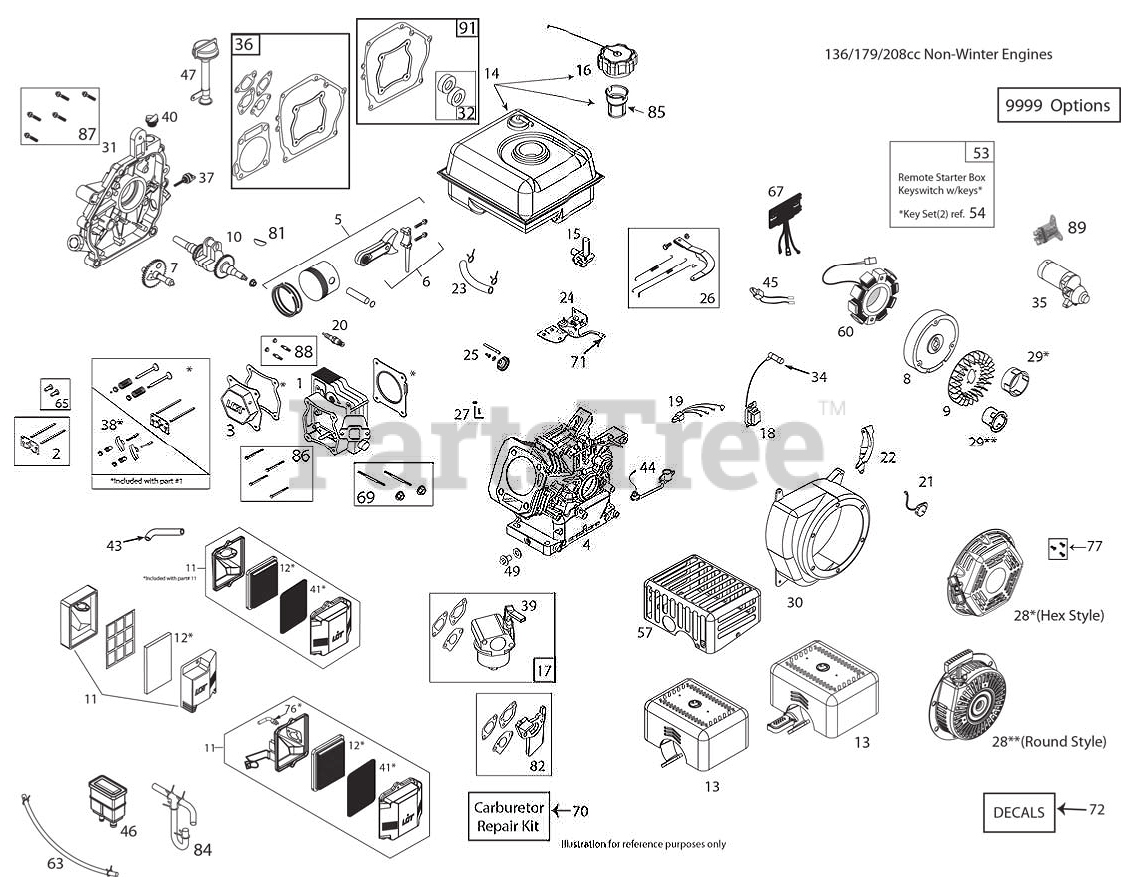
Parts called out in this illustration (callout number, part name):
1	CYLINDR.HEAD.SRV.KIT W/GASKET
2	KIT.PUSH.ROD.SRV(SK208-1001)
3	VALVE COVER ASSEMBLY
5	KIT.PISTON.SRV(SK208-1400)
7	KIT.CAMSHAFT.208CC.LCT
8	FLYWHEEL.E-START.2MAGNET.LCT
9	FLYWHEEL FAN 420586
10	CRANKSHAFT.KEYED.#14.LCT.208CC
11	AIR FILTER ASM. LCT.SK1362020.
12	FILTER.ASSEM.PANEL.LCT.208CC
13	KIT.49STATE.MUFFLER(SK208-2101
14	FUEL.TANK.2.7L.50STATE.LCT.208
15	FUEL.PETCOCK.1/4".LCT
16	CAP.FUEL.50STATE.W/CHAIN.LCT.
17	CARBURETOR.W/GASKETS.L33-2.EPA
18	IGNITION.COIL.LCT.
20	PLUG.SPARK.PLAT.SKSN2404.1
22	SHIELD.FLYWHEEL
23	FUEL HOSE KIT
24	SPEED CONTROL.MANUAL.LCT.
25	GOVENOR.GEARS ASM(SK2082900)
26	RP_IT.GOVERNOR.ARM(SUMMER ENG)
27	KIT.GOVERNOR.CRANK(SK208-3100)
28	RECOIL.STARTER.ROUND.BLACK
29	STARTER.DEEP.(ROUND STYLE
30	HOUSING BLOWER.BLK.ES LCT.
31	COVER.CRANKCASE.LCT.HIGH.OIL.F
32	SEAL KIT (2 PCS)
34	SPARK.PLUG.BOOT(SK2083800)
35	STARTER.ELECTRIC 120V
36	GASKET.KIT.208CC(SK2084300.1)
38	ROCKER ARM KIT
40	NON REMOVABLE PLUG
41	FOAM.PRE.FILTER.LCT.208CC
43	TUBE.BREATHER.LCT.208
47	TUBE ASSY HIGH OIL-FILL
49	KIT.OIL.DRAIN.PLUG(SK2089911
65	TAPPET.KIT.LCT.208CC
70	CARB.REPAIR.KIT.LCT.SK9900.2
71	KNOB.SPEED.CONTROL.RED.LCT.
77	BOLT.KIT.RECOIL.LCT.ALL.ENGINE
81	KEYS.FLYWHEEL.208/414CC.5PACK
82	SPACER.CARBURETOR.208CC.LCT
85	STRAINER.FUEL.TANK.LCT.208CC
86	KIT.BOLT.CYLINDER.HEAD.(4PC)
87	KIT.BOLT.CRANKCASE.COVER.6PC
88	STUD.MUFFLER.KIT.LCT
91	COVER CRANKCASE GASKET
9999	SHIELD.MUFFLER.MANIFOLD.LCT.
9999	BRACKET.MOUNTING.ES
9999	HIGH.ALTITUDE.JET.6000FT ANDUP
